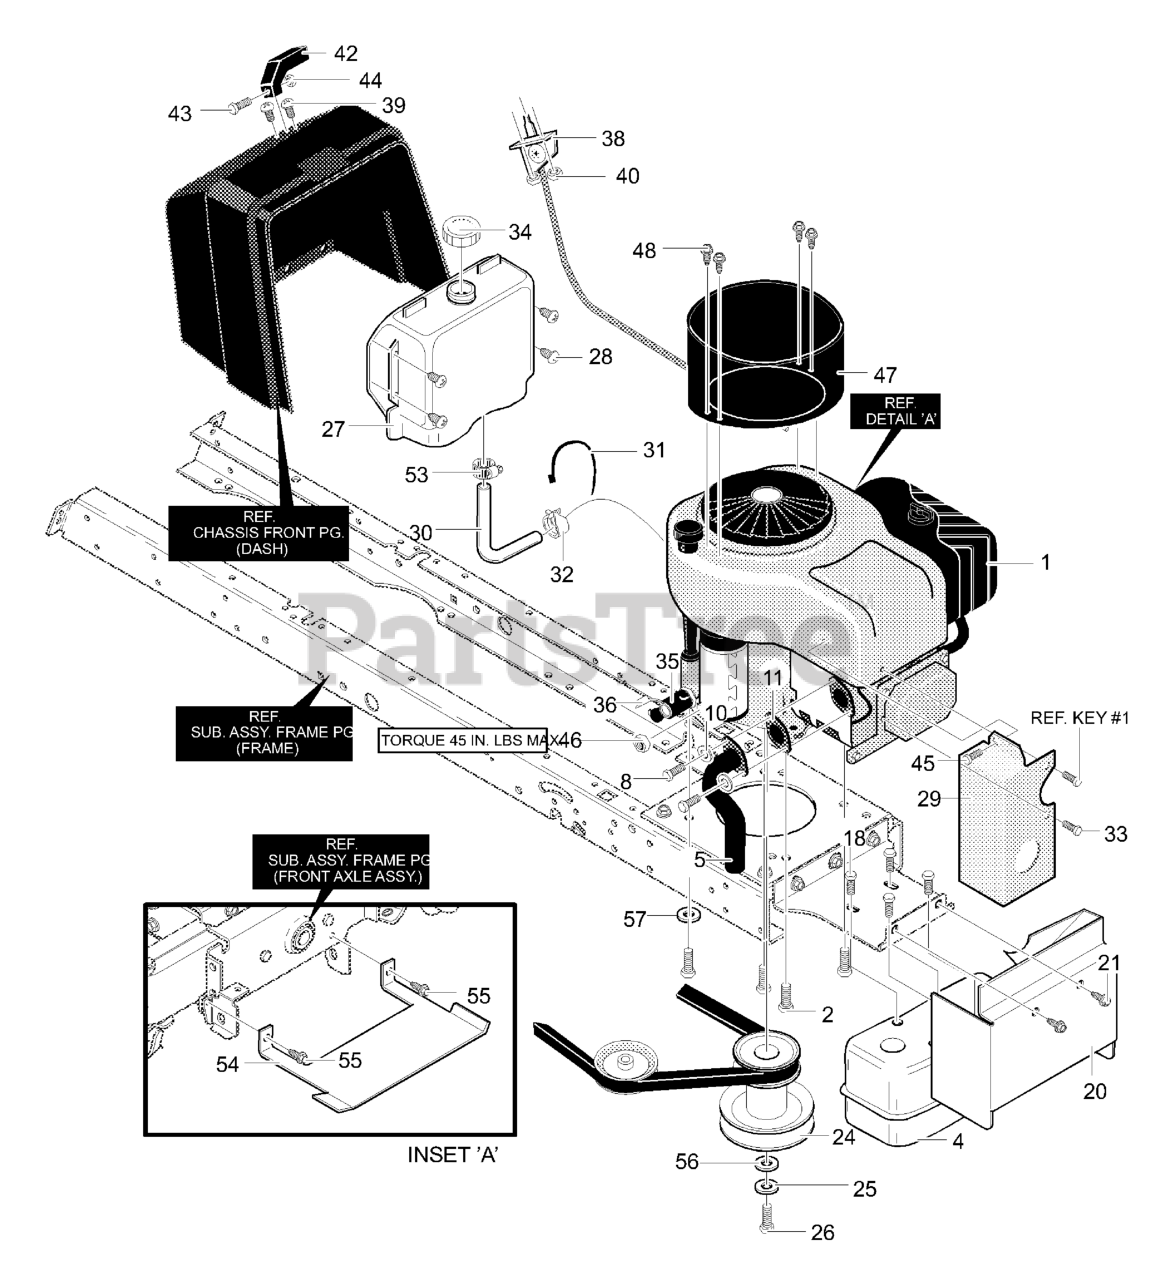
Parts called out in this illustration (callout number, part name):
1	15.5HP Engine
2	Screw, 3/8-16 x 1.25
4	Muffler, Single Cyclinder
5	Exhaust Tube
8	Screw, 5/16-18 x 0.75
10	Washer, Hvsptlk
11	GASKET, Exhaust
18	Screw, 1/4-20x.63
20	Heat Shield Lower Front
21	Screw, 5/16-18 x 0.75
24	Stack Pulley
25	Washer, Regsptlk
26	Screw, 7/16-20
27	Tank, Fuel 2 Gal.
28	Screw, #12x.50
29	Heat Shield, Side
30	Gas line 12 Inches
31	Cable Tie
32	Clamp, Fuel Clamp
33	Screw, 1/4-20x.50
34	Gas Cap
35	Oil Drain Valve Assembly
36	Cap, Oil Drain Valve
38	Throttle Control
39	Screw, 10-24x.63
40	Nut, #10-24
42	Knob, Throttle Control
43	Screw, #8-32
44	Nut, #8-32
45	Screw, 10-16x.50 Drill
46	Nut, 1/4-20
47	Plenum
48	Screw, #8-16x.38
52	Shield, Anti-Dehydration
53	Clamp, Hose Screw Type
54	Shield, Anti-Dehydration
55	Screw, 5/16-18 x 0.75
56	Flatwasher, ,480x1.00
57	Washer, Exlk
